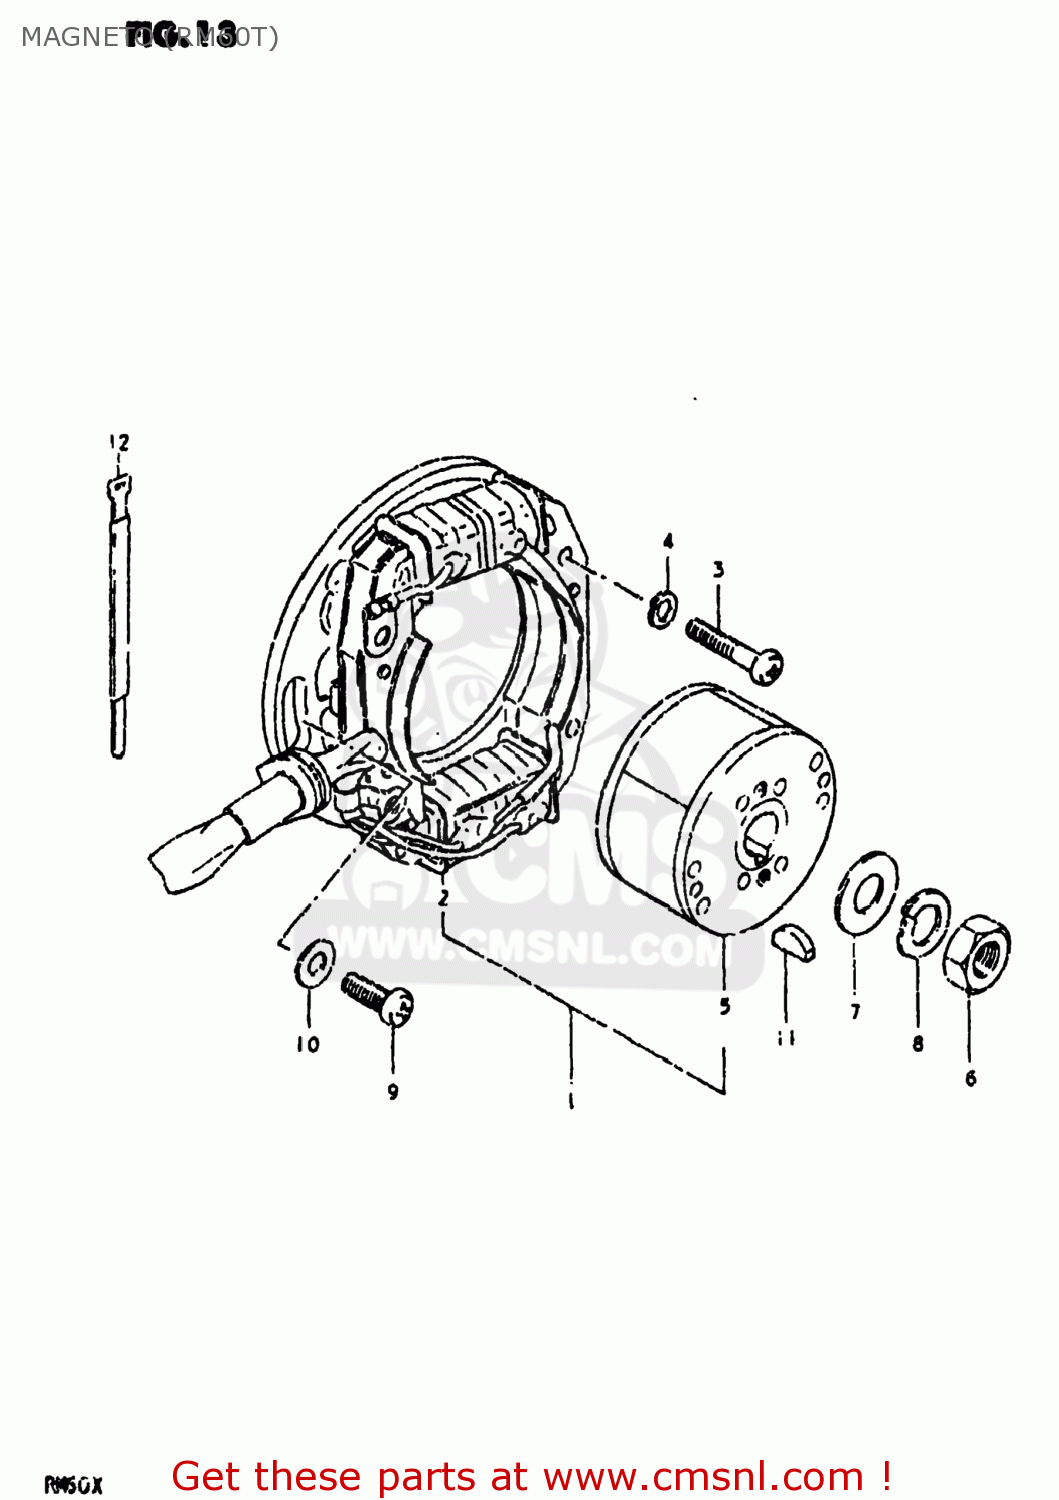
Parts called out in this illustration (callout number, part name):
1	MAGNETO ASSEMBLY
2	STATOR ASSEMBLY
3	SCREW
4	LOCK WASHER
5	ROTOR ASSEMBLY
6	NUT (10MM)
7	WASHER
8	LOCK WASHER
9	SCREW
10	WASHER
11	KEY 4MM
12	CLAMP
